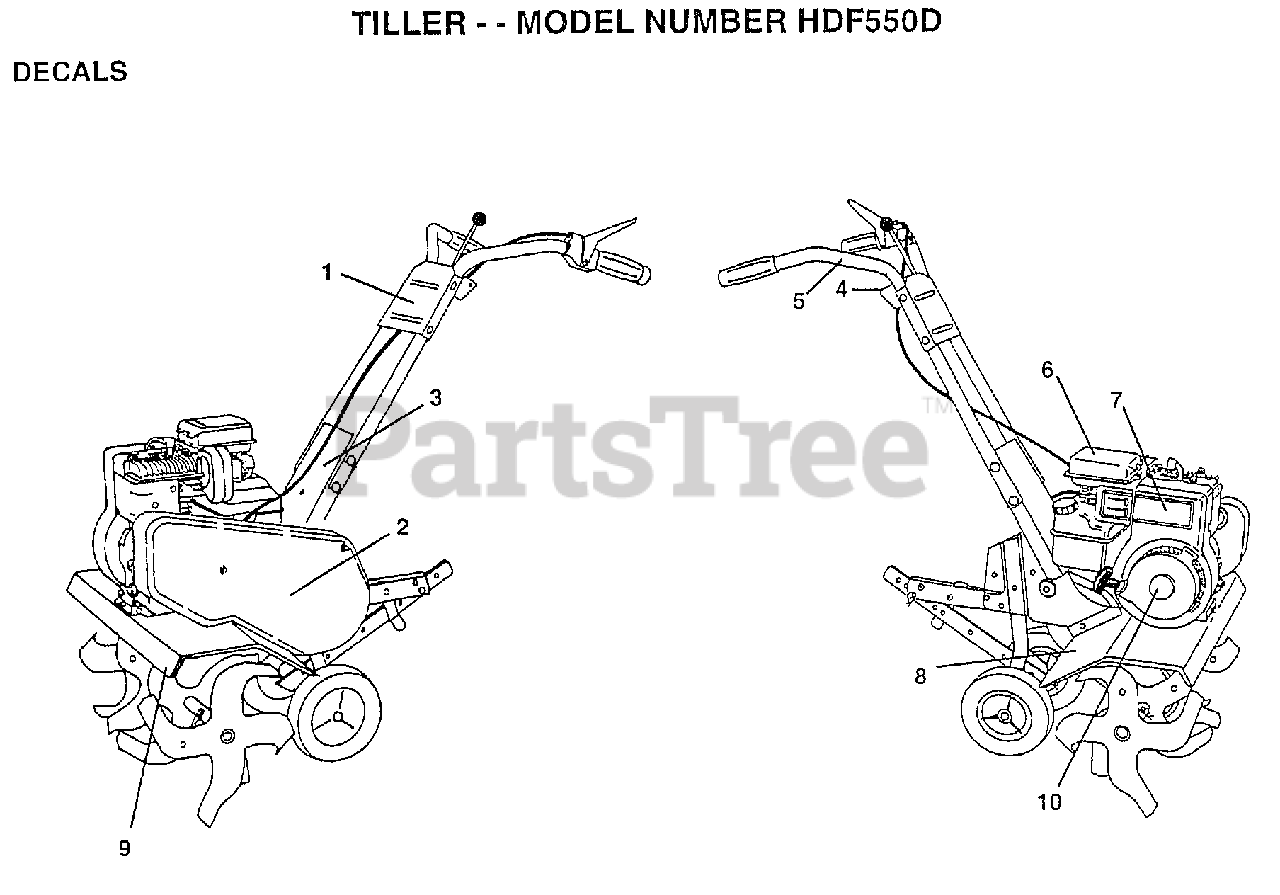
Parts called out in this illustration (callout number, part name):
1	"DECAL PANEL,CTRL"
2	"DECAL GUARD,BELT"
3	"DECAL PANEL,FORWD"
4	DECAL.PNL.CTRL.ES
5	DECAL.HAND.PLACE
6	DECAL.CAUTION.E/S
7	DECAL, BRIGGS & STRATTON
8	DECAL.WARN.ROT.TI
9	"DECAL SHIELD,TINE"
10	DECAL, 5 HP
